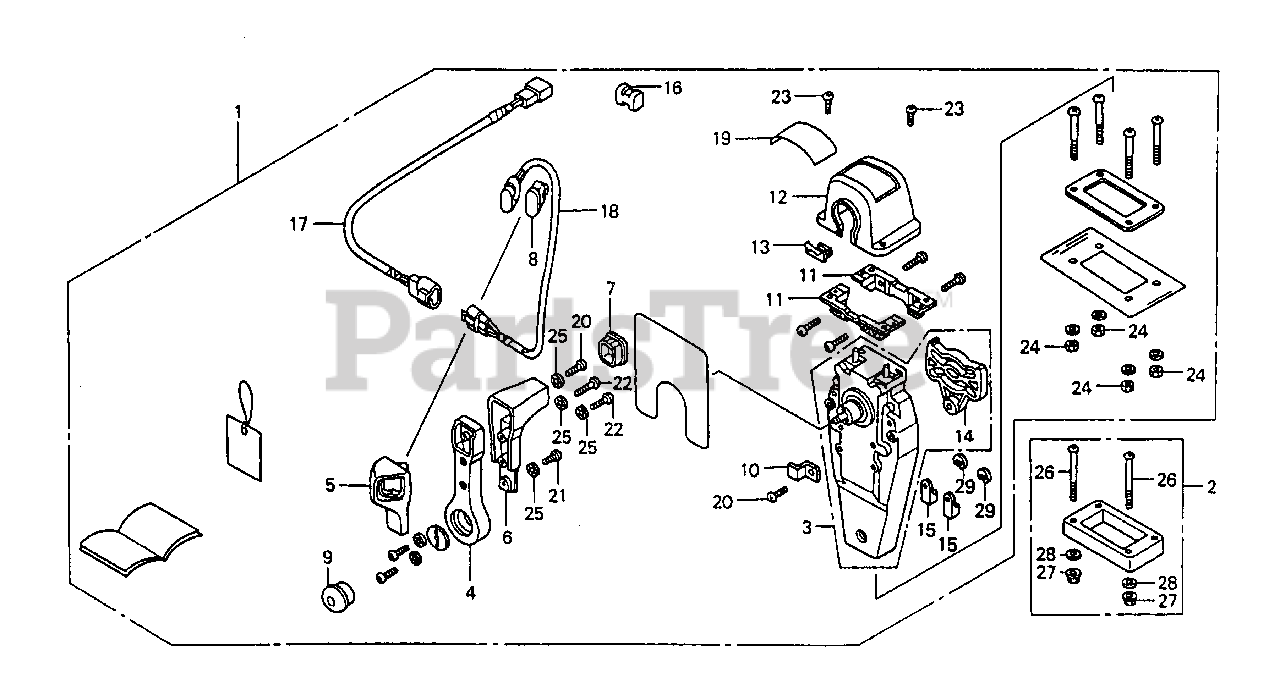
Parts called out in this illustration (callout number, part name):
1	BOX KIT, R. REMOTE CONTROL (TOP MOUNT SINGLE)
3	HOUSING ASSY., L. (INNER) (TOP MOUNT)
4	HANDLE, REMOTE CONTROL
5	COVER, L. GRIP
6	GRIP, REMOTE CONTROL HANDLE
7	CAP, GRIP
9	BUTTON, THROTTLE
10	PLATE, CABLE CLAMP
11	BRACKET, REMOTE CONTROL HOUSING
12	HOUSING, REMOTE CONTROL BOX
13	HOUSING, LEAD
14	PLATE, DWELL
15	CABLE, TERMINAL
16	SPACER, CABLE CLAMP
17	SUB-HARNESS A ASSY., POWER TRIM-TILT
18	SWITCH ASSY., POWER TRIM-TILT
19	MARK, REMOTE CONTROL TOP MOUNT SINGLE
19	MARK, REMOTE CONTROL (SINGLE)
20	SCREW, PAN (5X16)
21	SCREW, PAN (5X10)
22	SCREW, PAN (5X20)
23	SCREW, PAN (4X10)
24	NUT, HEX. (5MM)
25	WASHER, LOCK (5MM)
26	SCREW, PAN (5X65)
27	NUT, FLANGE (5MM)
28	WASHER, PLAIN (5MM)
29	E-RING (6MM)
